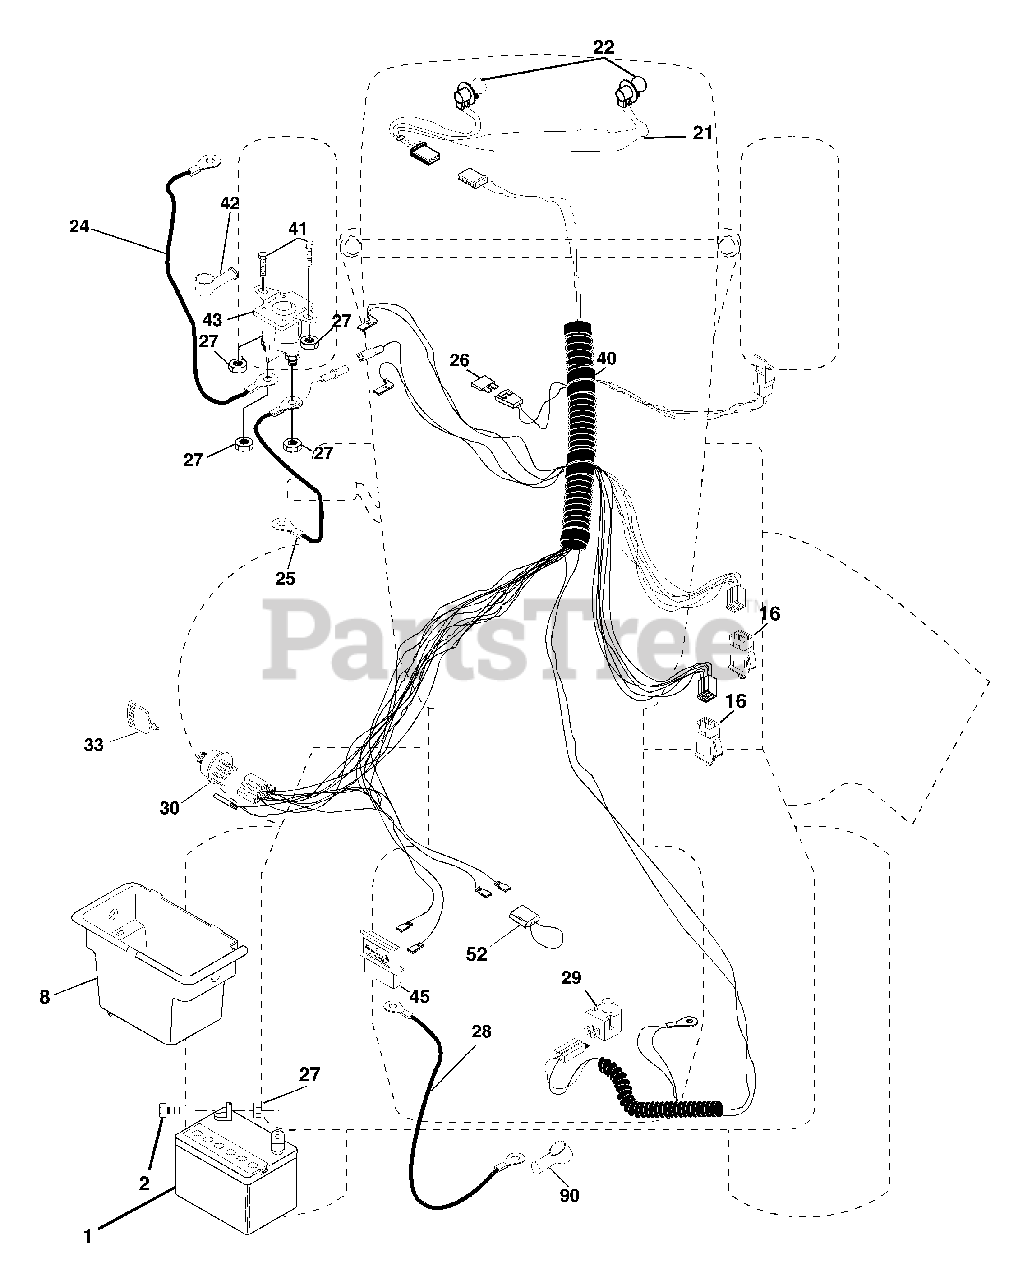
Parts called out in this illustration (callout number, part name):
1	Battery
2	Bolt Hex Hd 1/4-20unc X 3/4
8	Box Battery Fender
16	Switch Interlock
21	Harness Socket Light
22	Bulb, Light # 1156
24	Cable Battery
25	Cable Battery 6 Ga Red w/16 wire
26	Fuse
27	Nut Keps Hex 1/4-20 Unc
28	Cable Ground 6ga 12 black
29	Switch Plunger Nc Gray
30	Switch Ign
33	Key Ign Molded Generic
40	Harness Ign
41	Bolt Fin Hex 1/4-20uncx 1/2
42	Cover Terminal Red
43	Solenoid
45	Ammeter Rectangular
52	Protection Loop
90	Cover Terminal Battery
